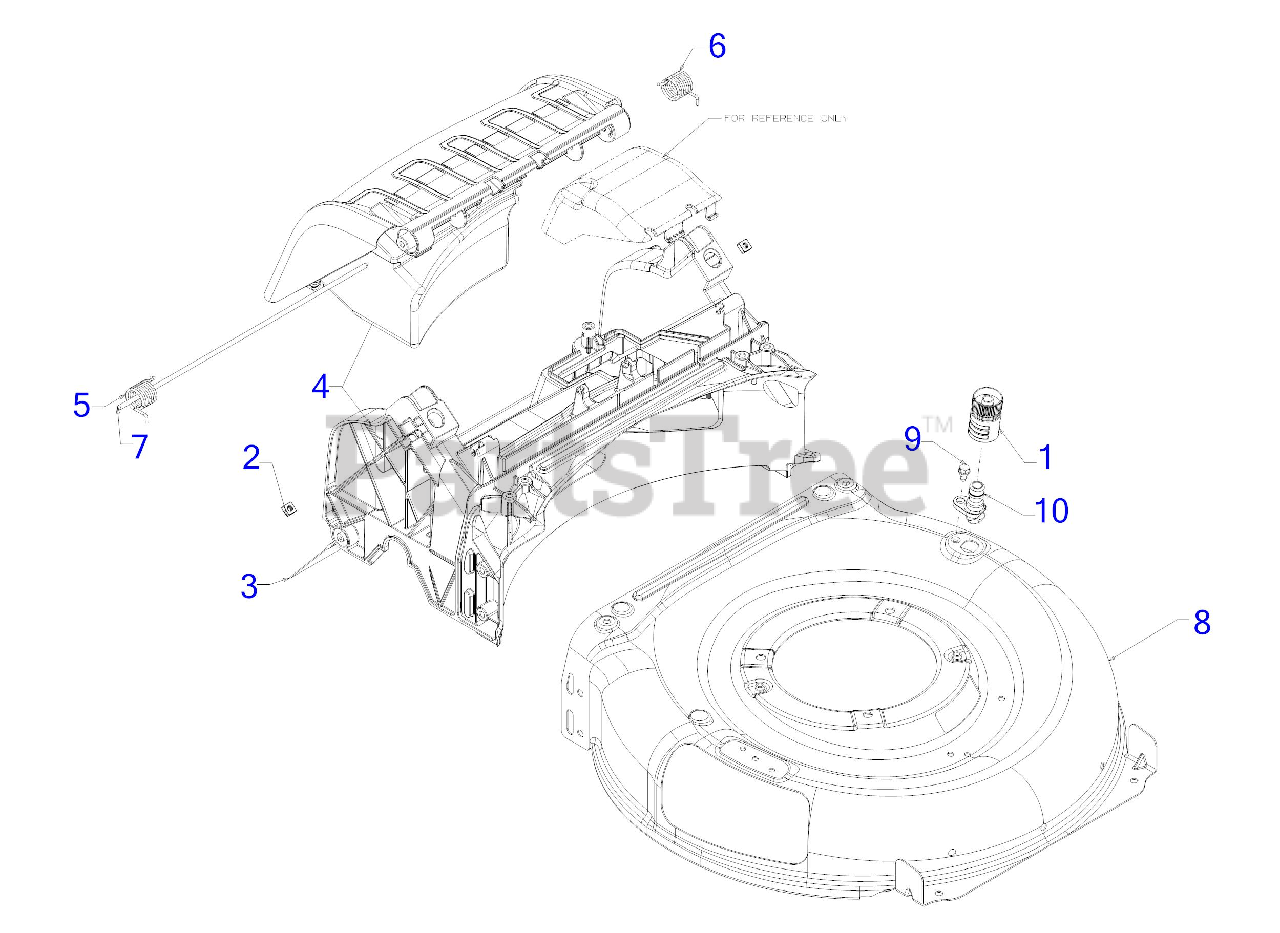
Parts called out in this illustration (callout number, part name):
1	WATER NOZZLE
2	SQUARE NUT 1/4-20
3	TRAILSHIELD
4	REAR BAG BAFFLE ASSEMBLY
5	TORSION SPRING (RH)
6	TORSION SPRING (LH)
7	REAR DOOR PIVOT ROD
8	21" DECK (3N1)
9	SHOULDER SCREW 1/4-20 x .50
10	DECK WASH NOZZLE
